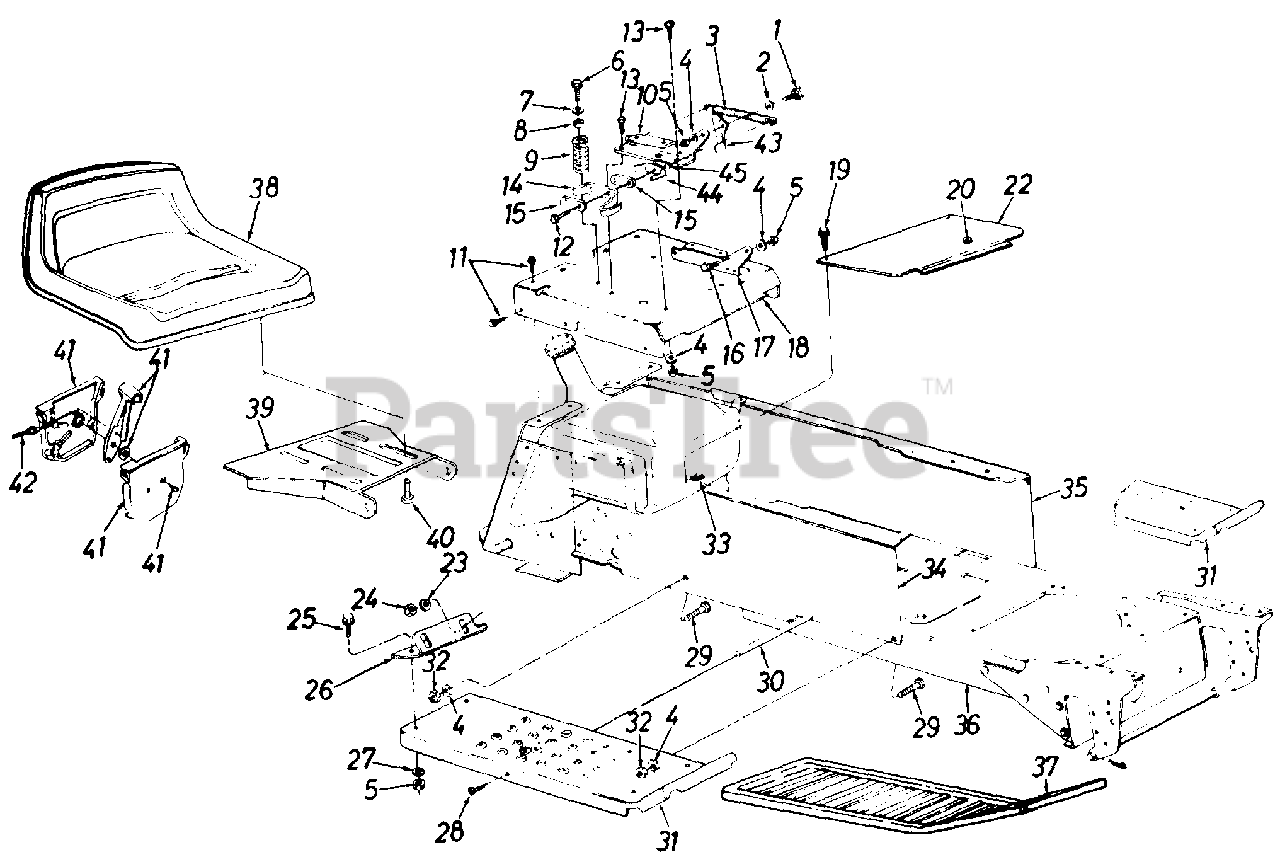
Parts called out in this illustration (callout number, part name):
1	Shld. Bolt .437" Dia. x .162"
2	Spr. Wash. .445" I.D.
3	Ext. Spring 5.31" Lg.
4	L-Wash. 5/16" I.D.
5	Hex Nut 5/16-18 Thd.
6	Hex Wash. Hd. Tap Scr. 5/16-18 x .7" Lg.
7	Fl-Wash. .344" I.D.
8	Bushing
9	Compression Spring
12	Hex Wash. Hd. AB-Tap Scr. #8 x .5" Lg.
13	Torx Hd. AB-Tap Scr. 5/16-18 x .75" Lg.
14	Spring Switch
15	Insulator Plate
16	Shld. Bolt .437" Dia. x .162"
20	Snap Bushing
22	Shift Cover
23	L-Wash. 1/4" I.D.
24	Hex Nut 1/4-20
25	Hex Bolt 5/16-18 x .75" Lg.
28	Truss Mach. Scr. 5/16-18 x .75" Lg.
29	Rib Neck Bolt 5/16-24 x .75" Lg.
30	Running Board Rod
33	Speed Nut #10Z
34	R.H. Side Frame
37	Rubber Foot Pad
38	Seat Ass'y. (8-7/8" High)
39	Seat Pivot Bracket
40	Hex Tap Scr. 3/8-36 x .75" Lg.
41	Throttle Control Box Ass'y.
42	Throttle Control Wire 35" Lg.
43	Seat Lift Bracket
44	Seat Spring Switch
45	Insulator Boss Plate
